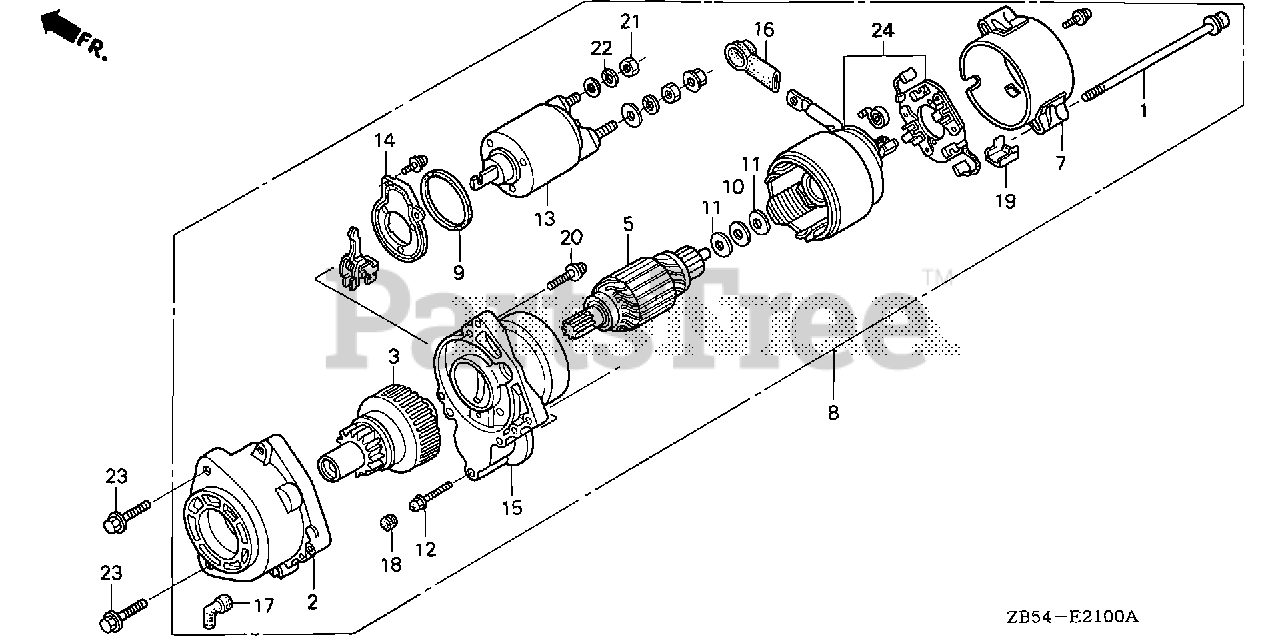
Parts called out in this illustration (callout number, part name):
1	BOLT, THROUGH (MITSUBA)
2	COVER, GEAR
3	GEAR ASSY.
5	ARMATURE (MITSUBA) (N/A: SEE ASSEMBLY)
7	BRACKET ASSY., RR.
8	STARTER MOTOR ASSY.
9	RING, SQUARE (MITSUBA) (NOT AVAILABLE)
10	WASHER, THRUST (1.2) (MITSUBA)
11	WASHER, THRUST (0.2)
12	SCREW-WASHER (4X28) (MITSUBA)
13	SWITCH ASSY.
14	PLATE, FR. (NOT AVAILABLE)
15	BRACKET ASSY., FR.
16	COVER, TERMINAL
17	TUBE, LABYRINTH
18	BUSH, RUBBER
19	COVER, DRAIN
20	SCREW-WASHER (6X30)
21	NUT, HEX. (8MM)
22	WASHER, SPRING (8MM)
23	BOLT, FLANGE (8X20) Use up to Engine SN 1609606.
24	STATOR SET
